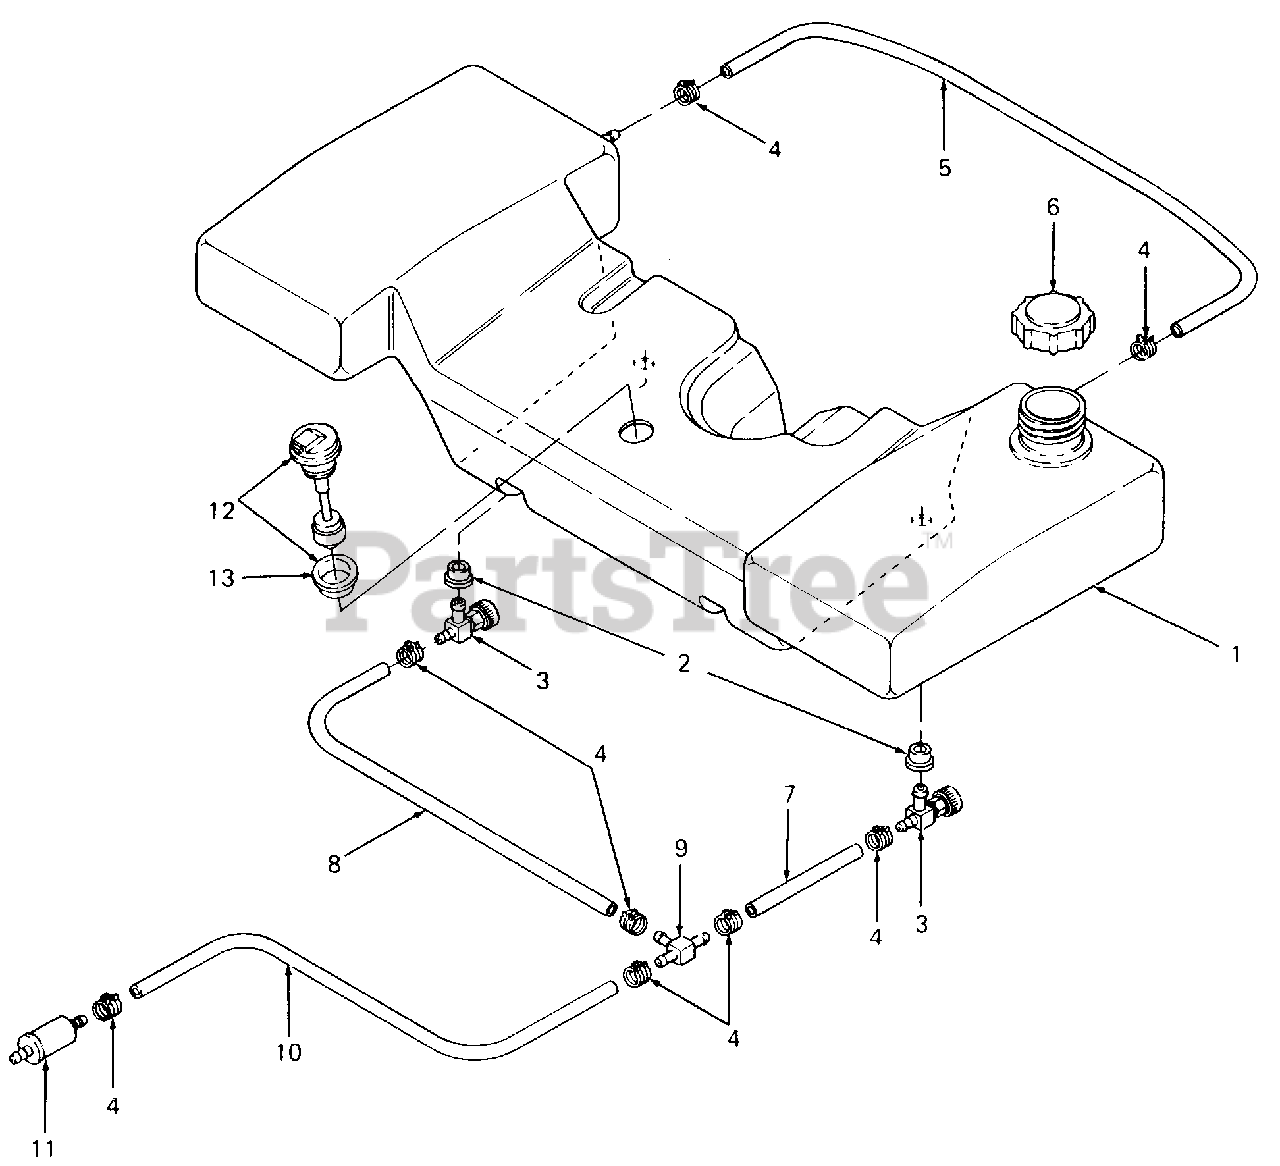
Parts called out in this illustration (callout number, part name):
1	Tank, Fuel
2	Bushing
3	Valve, Fuel Shutoff
4	Clamp, Hose
5	Line, Fuel -24" Lg
6	Cap, Fuel
7	Line, Fuel -5" Lg
8	Line, Fuel -17" Lg
9	T-Fitting
10	Line, Fuel -41" Lg
11	Filter, Fuel
12	Sensor, Low Fuel
13	Bushing, Rubber
